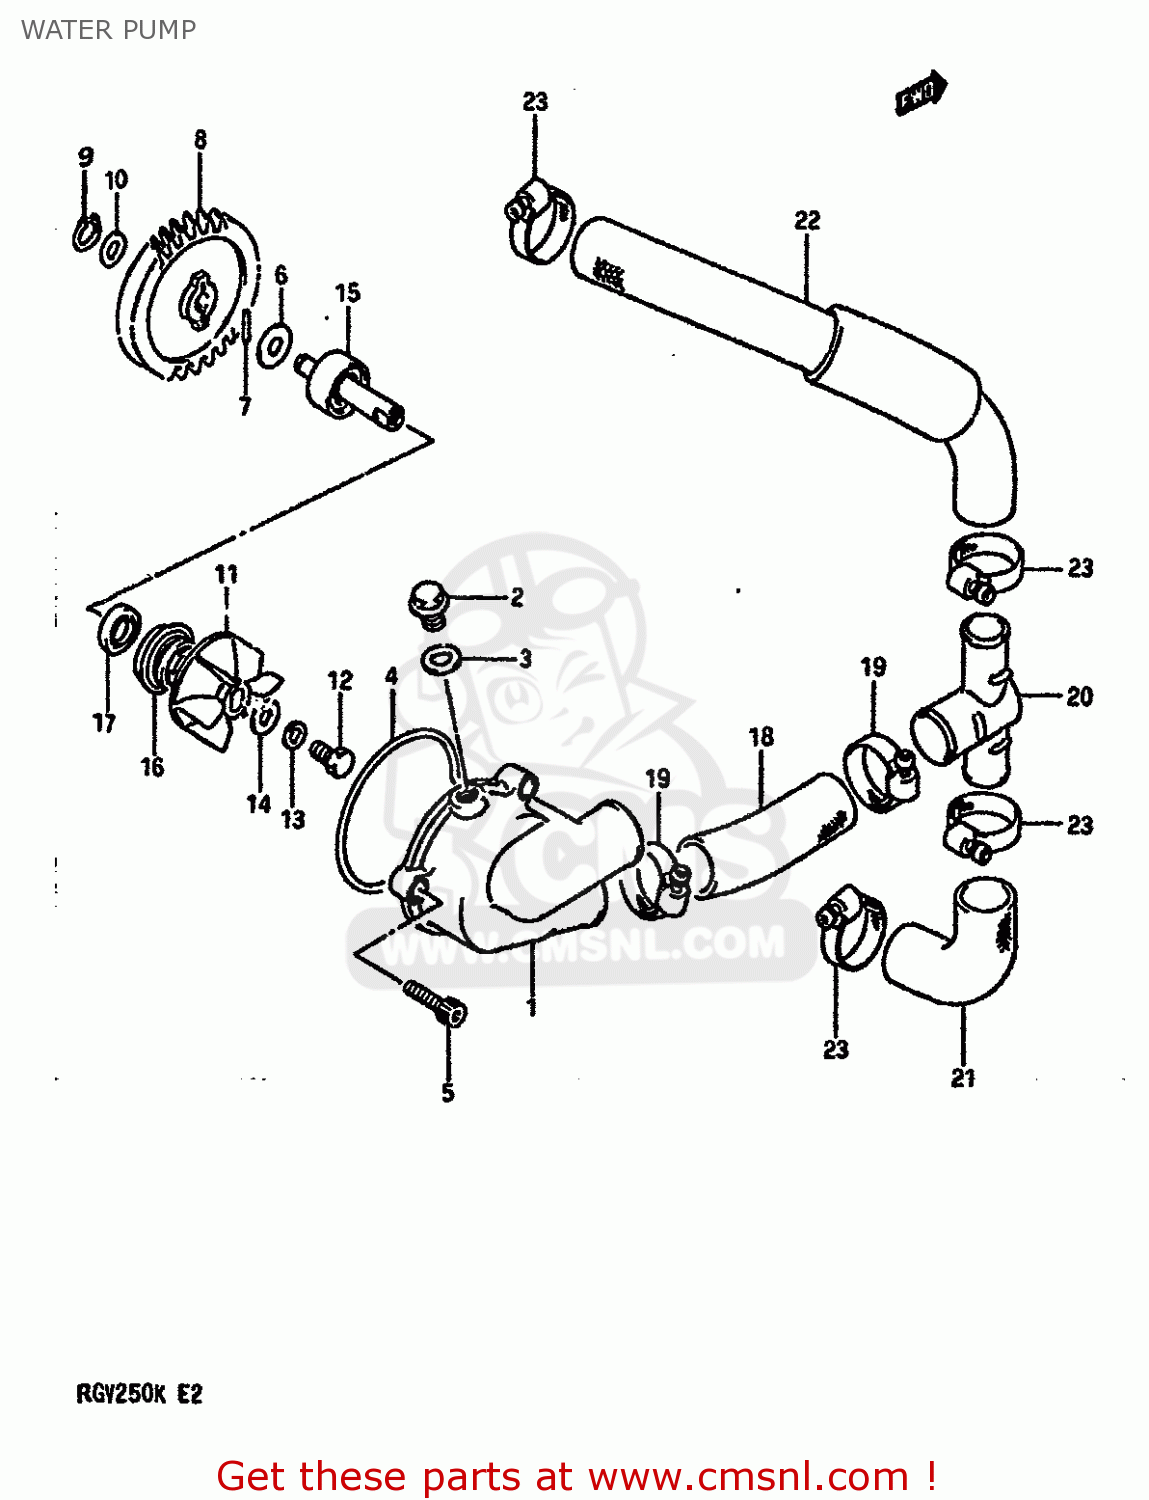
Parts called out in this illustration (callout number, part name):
1	CASE,WATER PUMP
2	BOLT,DRAIN
3	GASKET 8.2X14X1 (NAS)
4	O RING,WATER PUMP CASE
5	BOLT ,6X20
6	WASHER
7	PIN(2.5X19.8)
8	GEAR,WATER PUMP DRIVE(NT:31)
9	CIRCLIP
10	WASHER
11	IMPELLER,WATER PUMP
12	BOLT(6X13)
13	WASHER
14	GASKET(6X15X2.2) (NAS)
15	SHAFT,WATER PUMP
16	SEAL,MECHANICAL
17	SEAL,OIL(10X20X5)
18	HOSE,WTR PUMP OUTLET
19	CLAMP
20	UNION,WTR HOSE THREE WAY
21	HOSE,CYLINDER INLET NO.1
22	HOSE,CYLINDER INLET NO.2
23	CLAMP
